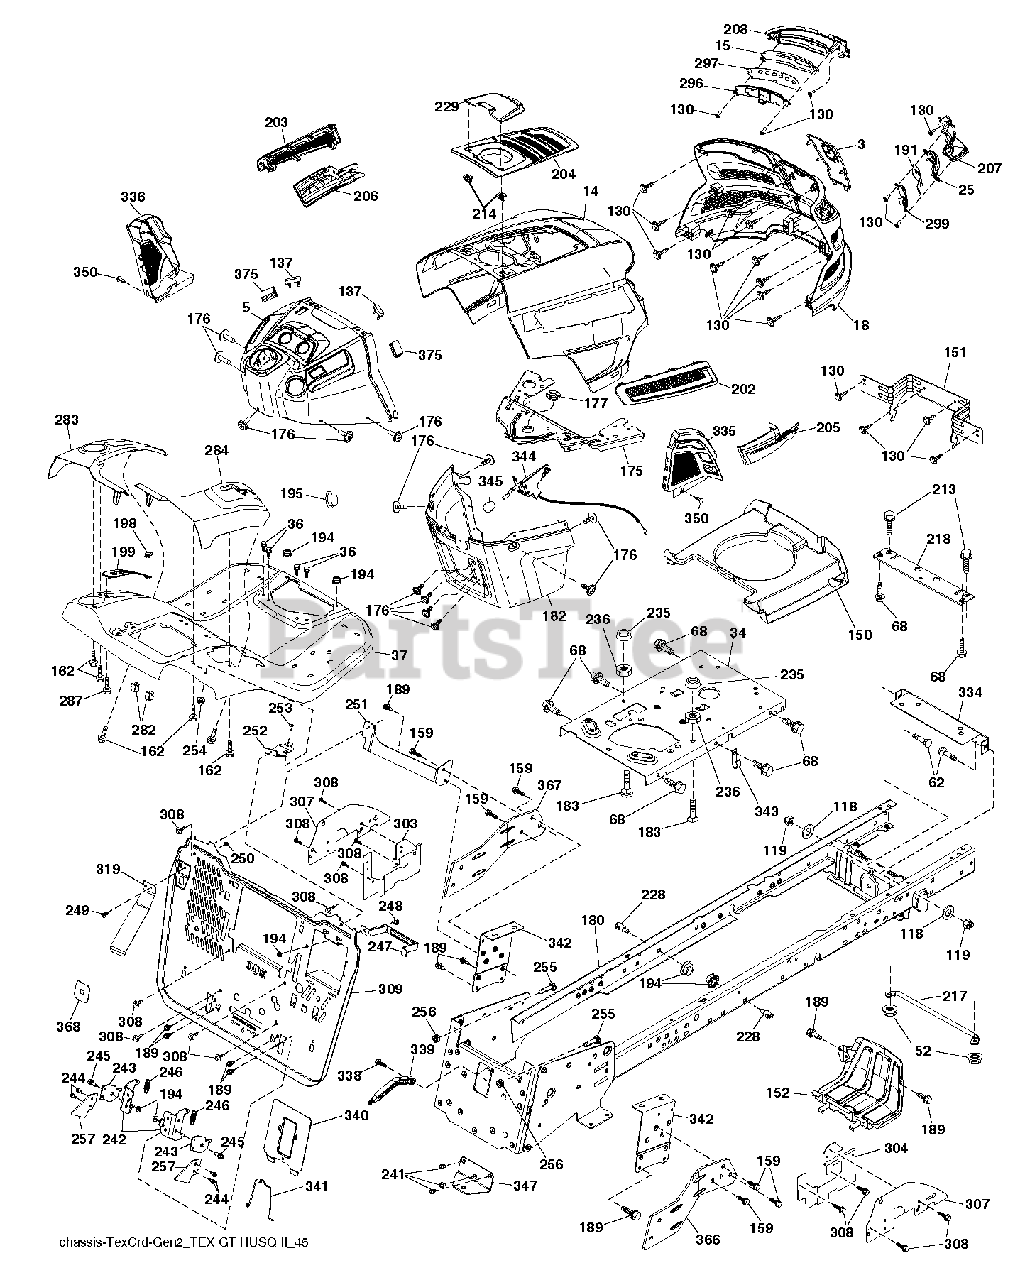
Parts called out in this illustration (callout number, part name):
3	APPLIQUE.SUBASM.GT.HUSQ.II
5	DASH.UPP.GT2.DUAL.RD.
14	HOOD.ASM.HUSQVARNA.GT.TEX.ORAN
15	LED LIGHT.LH
18	GRILLE SUBASM.GT.II.LOW.HDLGHT
25	LENS.RH
34	PLATE.ENGINE.10GA.CRD.GENII
36	SCREW 5/16"
37	FENDER.TEX.SRD.CRD.FRN.GUARDS
52	LOCKNUT
62	BOLT D
68	SCREW LT
118	WASHER
130	SCREW.#10 X 0.750.BOS
137	BUMPER DASH
150	AIR.DUCT.GTV.BLACK
151	BRACKET.PIVOT.HOOD.GT.HUSQ.II
152	SHIELD.BROWNING.PNT.GT.V2
159	SCREW, 3/8-16X3/4
162	SCREW.HI-LO.CONSOLE
175	PLATE.CROSSMEMBER.HUSQ
176	SCREW.#10-24X5/8.RN.QU
177	BUSHING STEERING
180	WELDMENT.CHASSIS.TEX.CRD.GEN.2
182	DASH.LOWER.COMMON.12V.ADAPTOR
183	BOLT.5/16-18X1-1/4 FULL THD
189	SCREW
191	INSERT INFLECT.RH
194	NUT LOCK HEX FLANGE 5/16-18
195	PLUG.HOLE.DASH.LOWER.12V.BLK
198	INDICATOR.DECK.LIFT.RED
199	PLATE DECK LIFT
202	VENT.SIDE.RH.GT.HUSQ.II.
203	VENT.SIDE.LH.GT.HUSQ.II.498
204	VENT.TOP.EXTERNAL.FILL.GT2.GRE
205	SIDE.TRIM.RH.GT.HUSQ.II
206	SIDE.TRIM.LH.GT.HUSQ.II.GRAY
207	BEZEL GT2 LED RH W/ LOWER.ATT
208	BEZEL GT2 LED LH W/ LOWER ATT
213	BOLT
214	CLIP.RETAINER.TINNER.
217	ROD.PIVOT.HOOD
218	X-PIECE.HOOD.STOP.NON/
228	STUD.FASTNER.W/ANTI-ROTATE
229	LID.EXT.FILL.GT.HUSQ2.BLACK
235	SPACER FENDER
236	NUT.CENTERLOCK.5/16-
241	SCREW 5/16-18X1
242	LATCH.BRACKET.TCRD.GEN 2.5.BAG
243	ARM.PIVOTING.TCRD.GEN2.5.BAGGE
244	SCREW
245	BOLT, SHOULDER
246	SPRING.TCRD.GEN2.5.BAGGER.EXT
247	STRAP.BATTERY.TCRD.GE
248	BOLT
249	SCREW.BUTTONHD.10-24X1/2.(2 2)
250	NUT 10-24 NYLOC
251	BRKT.TOPSPPRT.BCKPLT.
252	BRKT.TOPSPPRT.BCKPLT.RH.CRD2.5
253	BOLT
254	NUT T
255	BOLT.CROSSDRILLED.381
256	Hex Nut, 3/8-16
257	LATCH.BAGGER.TEXCRD2.5
282	CLIP.RETAINER.CONSOLE.LT.HUSQ
283	CONSOLE.DECKLIFT.CRDII.498
284	CONSOLE.PEDAL.HYDRO
287	SCREW 1/4X20
296	LED LIGHT.LH
297	INSERT REFECT LH
299	LED LIGHT.RH
303	SHIELD.LWR.LH.LT.30"CRDSRD.PNT
304	SHIELD.LWR.RH.LT30DECK.PNT.BLK
307	SHIELD.UPPER.CRD.SRD.ISO
308	BOLT, 5/16-18 X 1 3/4
309	BACKPLATE.TEXCRD2.5.B
319	LEVER.BAG.CRDII.ANTIROTATION
334	BRACKET.ENGINE
335	COVER.LOWER.DASH.RH.BLACK
336	COVER-LH.LOWER.DASH.GT2.BLACK
338	BOLT BOLT SHOULDER
339	LEVER LEVER BAGGER
340	BATTERY.DOOR.TCRD.GEN
341	LATCH.BATTERY.DOOR.TC
342	SUPPORT SUPPORT FENDER
343	CLIP CLIP
344	CONTROL.EZ.MULCH.TEX/CRD
345	RP KNOB.OVAL.TAPERED.3/8-16BLK
347	HITCH HITCH TOW TEX CRD GEN 2
350	CLIP.X-MAS.TREE
366	BRACKET.RH.FRONT.BAGGER.BLACK
367	BRACKET.LH.FRONT.BAGGER.BLACK
368	FULL.LEVER.BAGGER.TEX.CRD
375	BUMPER CLIP-ON. DASH 1"
